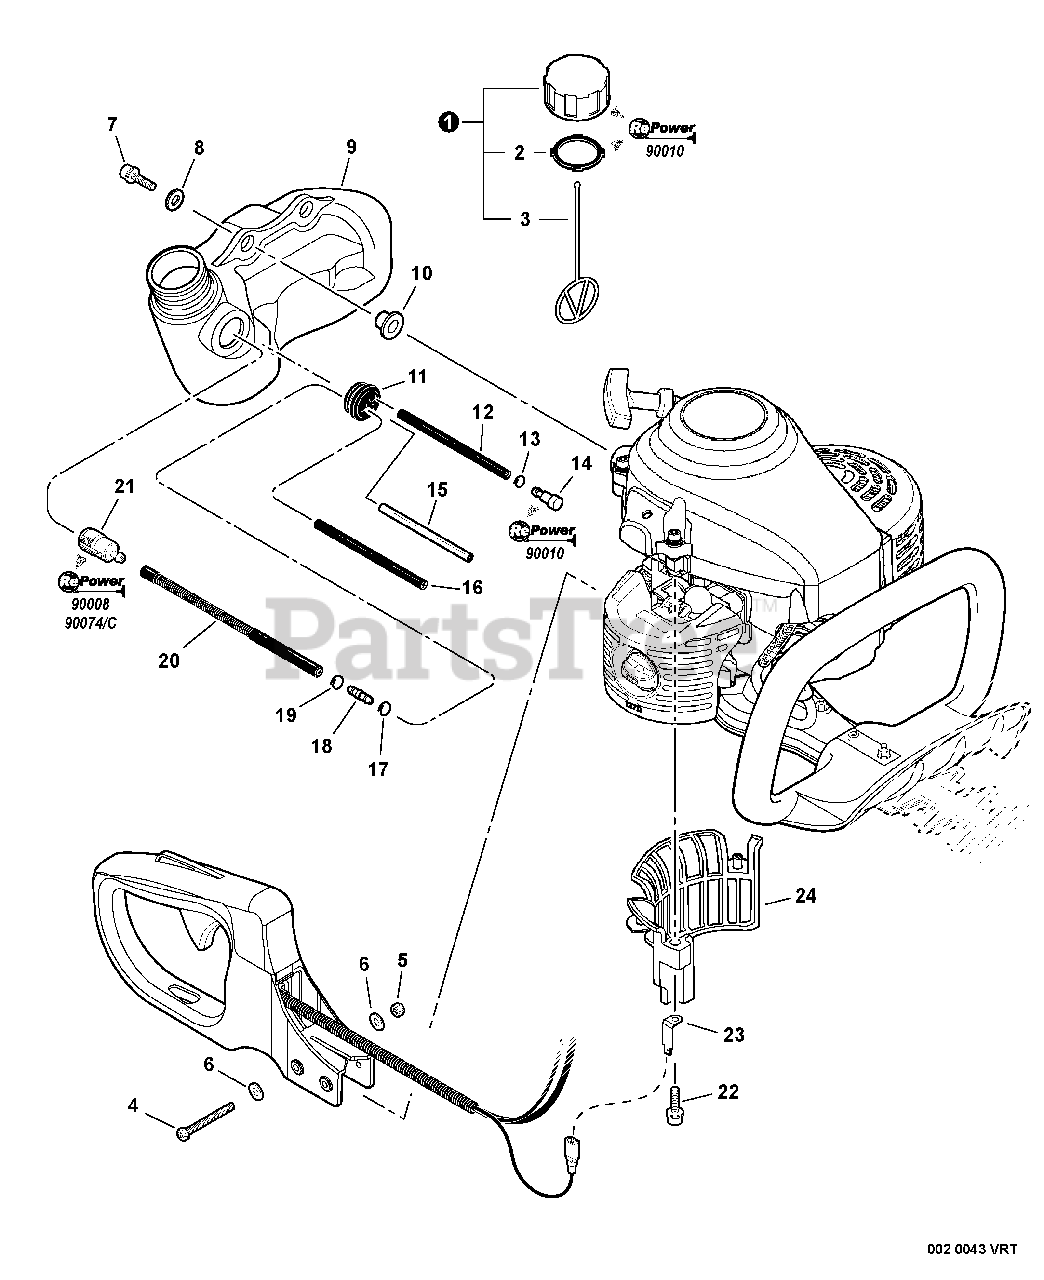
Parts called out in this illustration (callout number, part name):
1	CAP ASSY, FUEL
2	GASKET, FUEL CAP
3	CONNECTOR, CAP L= 123
4	SCREW 5×45
5	NUT, LOCK M5
6	WASHER, FLAT 5.5×10×0.8
7	BOLT 5×20
8	WASHER 5.5×12×0.8
9	TANK, FUEL
10	COLLAR 5
11	GROMMET, FUEL
12	PIPE - 3×5×65 -- BLACK
13	CLIP 6.6 MM
14	VENT ASSY
15	PIPE, FUEL 3×6×75 CLEAR
16	PIPE, FUEL 3×6×105 BLACK
17	CLIP 6 MM
18	CONNECTOR
19	CLIP Ø6.5 MM
20	PIPE, FUEL 3×7×100 FLEXIBLE
21	FILTER, FUEL
22	BOLT 5×16
23	CONNECTOR
24	SHIELD, DEBRIS
25	FILTER KIT - REPOWER
26	CAP/VENT KIT - REPOWER
27	TUNE-UP KIT - REPOWER
